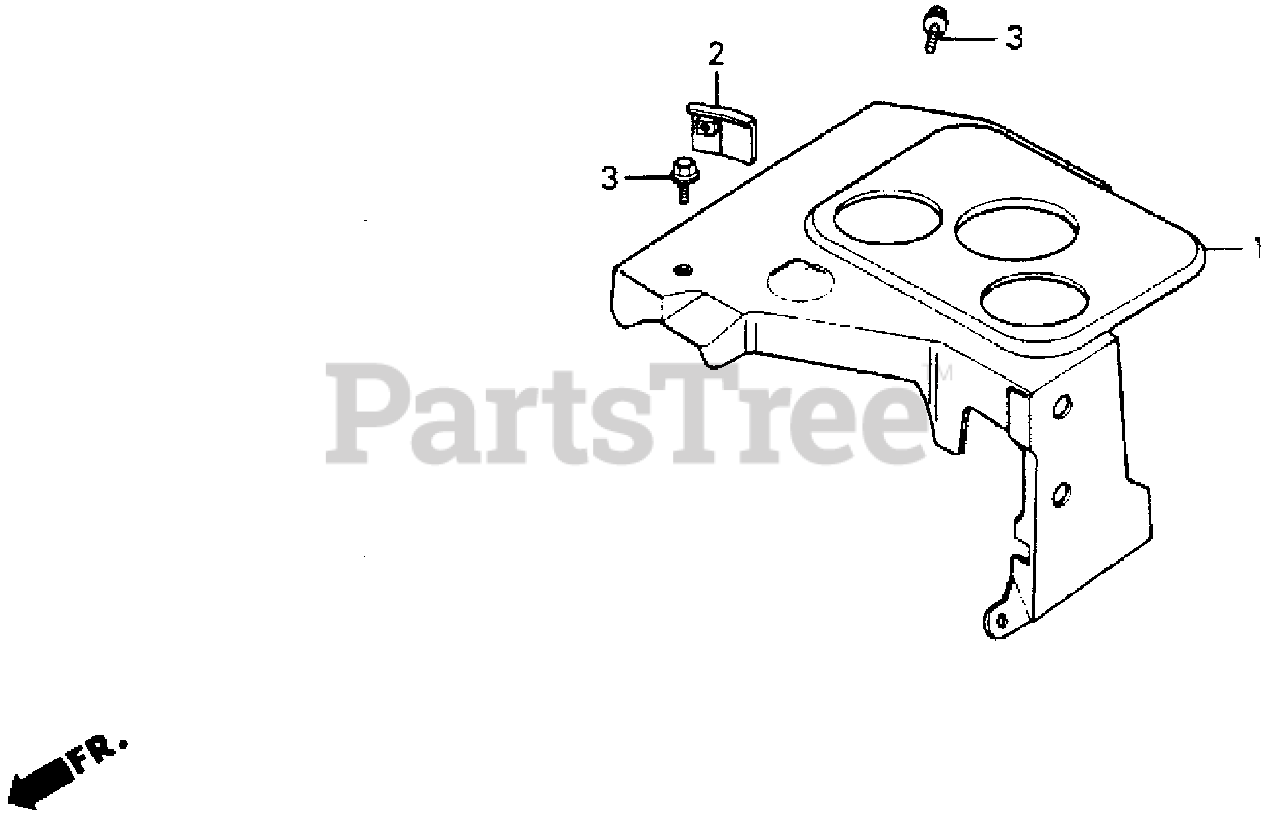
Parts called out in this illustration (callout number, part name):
1	COVER, ENGINE CONTROL
2	STOPPER, THROTTLE LEVER
3	BOLT, FLANGE (6X10)
